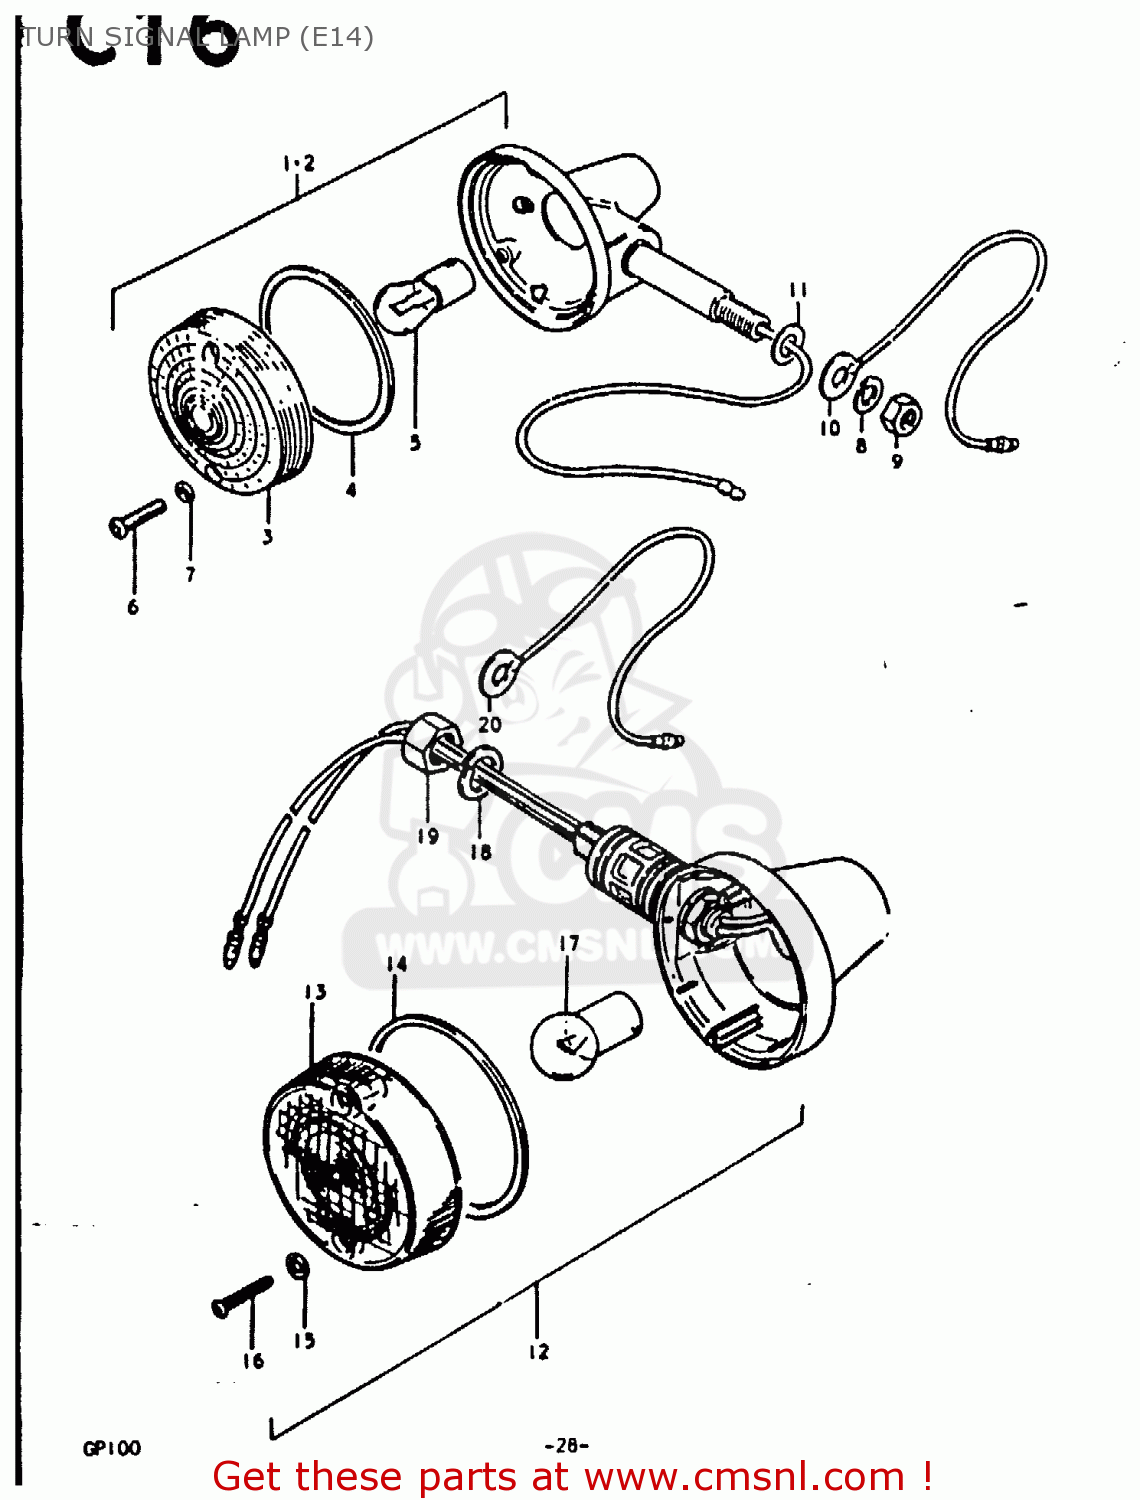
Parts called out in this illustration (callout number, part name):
12	LAMP ASSY, REAR TURN SIGNAL LAMP
13	LENS
14	GASKET (NAS)
15	GASKET (NAS)
16	SCREW TAPP.
17	BULB(6V8W,STANLEY,A4115)
18	WASHER,LOCK 12
19	NUT
20	LEAD WIRE,EARTH
